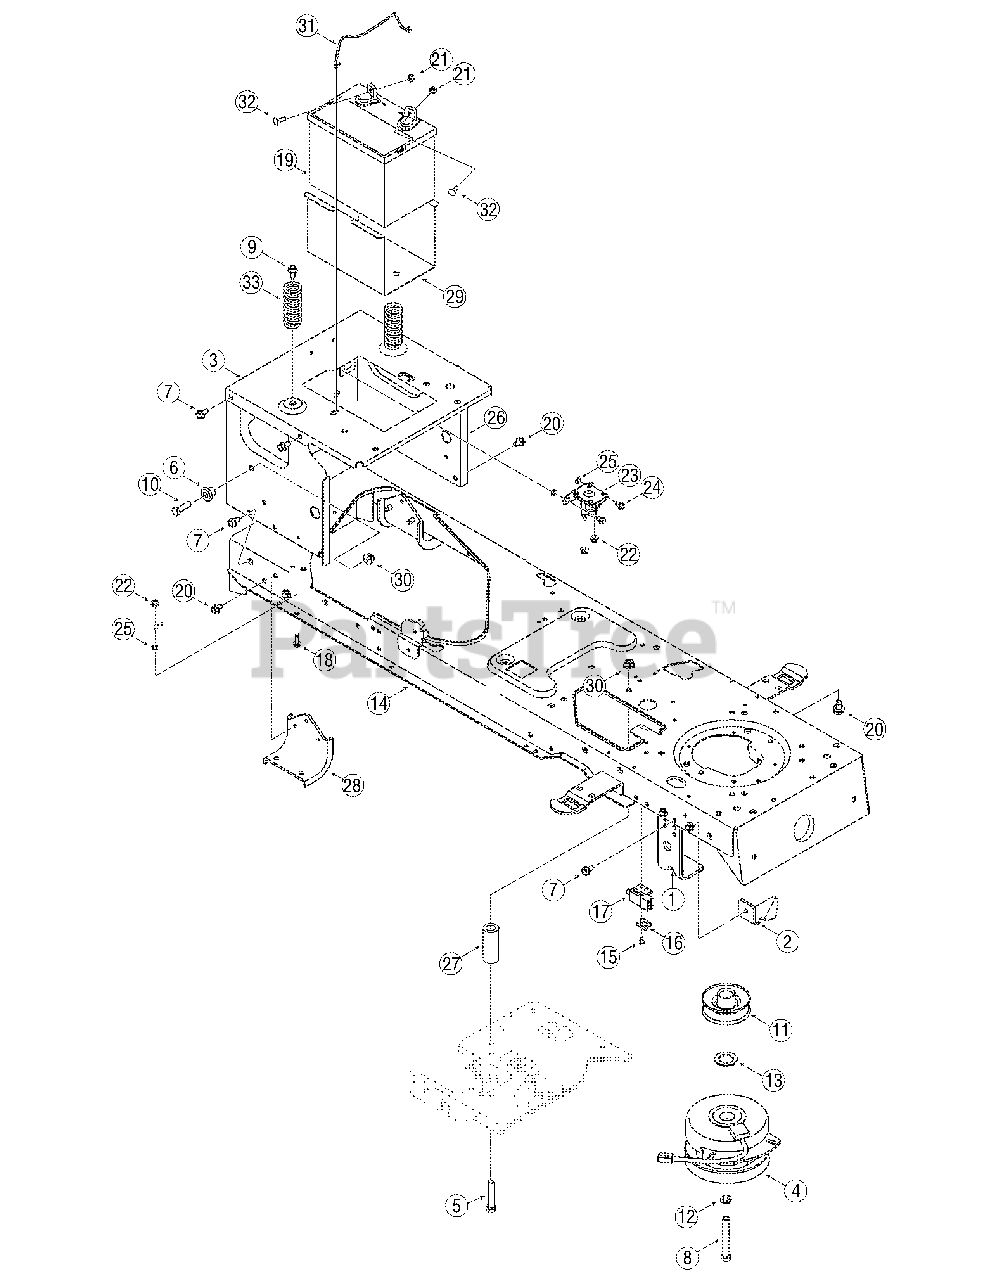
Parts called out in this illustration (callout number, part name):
5	Hex Screw, 3/8-16 x 2.25
6	Spacer, Shldr,.38 x 1.0 x.70
7	AB Screw, 5/16-12 x.75
8	Hex Screw, 7/16-20 x 3.50
9	Screw, LD, 5/16-18 x.750
10	Screw, 3/8-16 x 1.25
11	Engine Pulley
12	Lock Washer
13	Flat Washer, 1.031 x 1.620 x.095
16	Switch Plate
17	Switch
18	TT Screw 1/4-20 x 0.75
19	12 V Battery, 235 CCA
20	TT Screw 5/16-18 x 0.5
21	Hex Sems Nut, 1/4-20
22	Flange Lock Nut, 1/4-20
23	Solenoid, 12-Volt, 100 Amp
24	Self Tapping Screw, 1/4-20 x.5
25	Lock Washer, 1/4
26	Upper Frame
31	Battery Hold Rod
32	Screw, Carriage, 1/4-20 x.75
33	Compression Spring, 1.28 x 3.125
